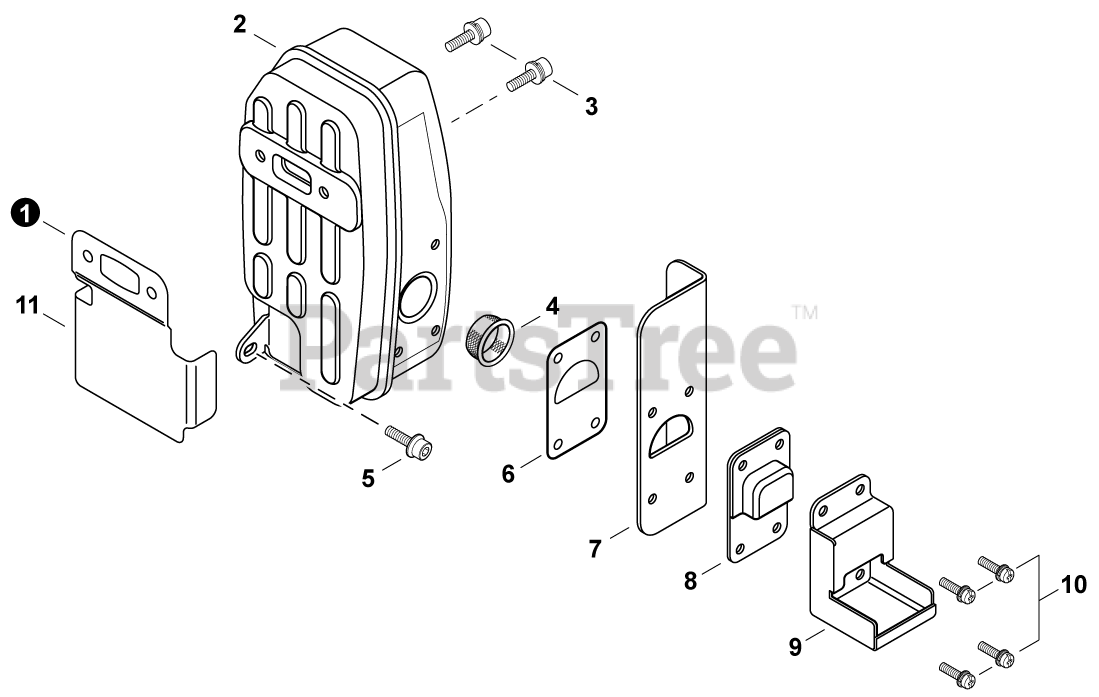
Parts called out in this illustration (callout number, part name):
1	HEAT SHIELD, EXHAUST
2	MUFFLER
3	BOLT, FLANGE 6×20
4	SCREEN, SPARK ARRESTER
5	BOLT 5×14
6	GASKET, EXHAUST
7	HEAT SHIELD, EXHAUST
8	GUIDE, EXHAUST
9	GUIDE, EXHAUST
10	SCREW 4×14
11	GASKET KIT
